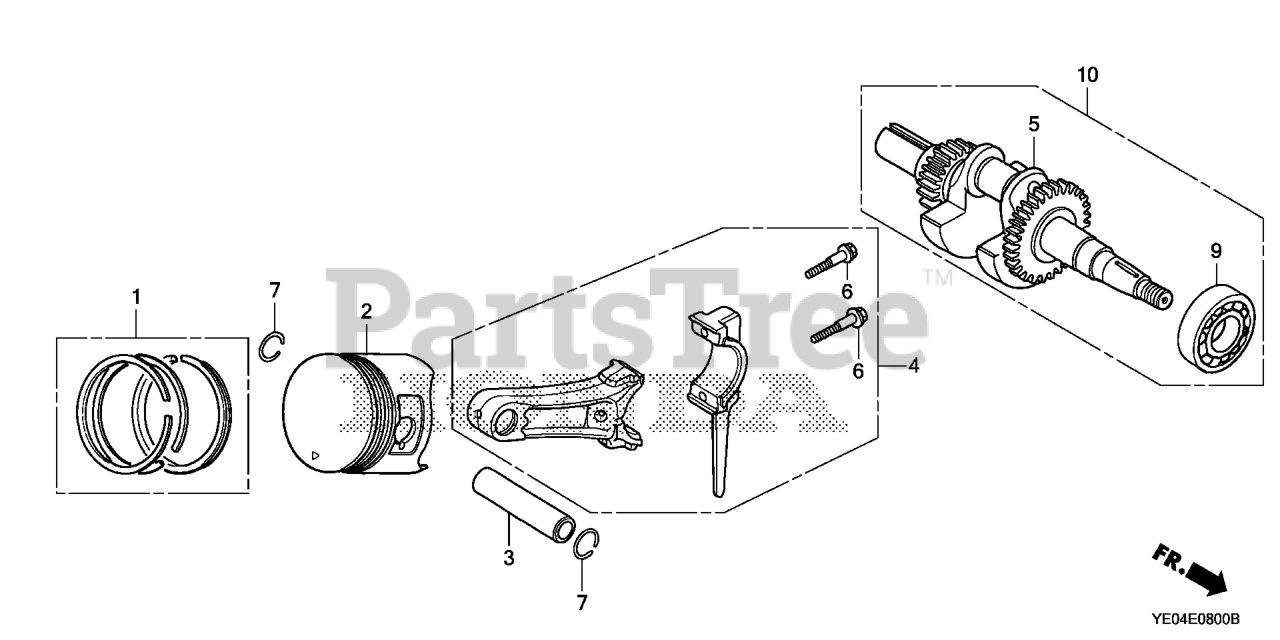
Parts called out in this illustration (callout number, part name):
1	RING SET, PISTON (0.25) Use from Engine SN 1314913.
1	RING SET, PISTON (0.25) (RIKEN)
1	RING SET, PISTON (0.50) (TPR)
1	RING SET, PISTON (0.50) (RIKEN)
1	RING SET, PISTON (STD) (RIKEN)
2	PISTON (STD)
2	PISTON (0.25)
2	PISTON (0.50)
3	PIN, PISTON
4	ROD ASSY., CONNECTING (UNDER SIZE)
4	ROD ASSY., CONNECTING
5	CRANKSHAFT
6	BOLT, CONNECTING ROD (6X34.5)
7	CLIP, PISTON PIN (18MM)
